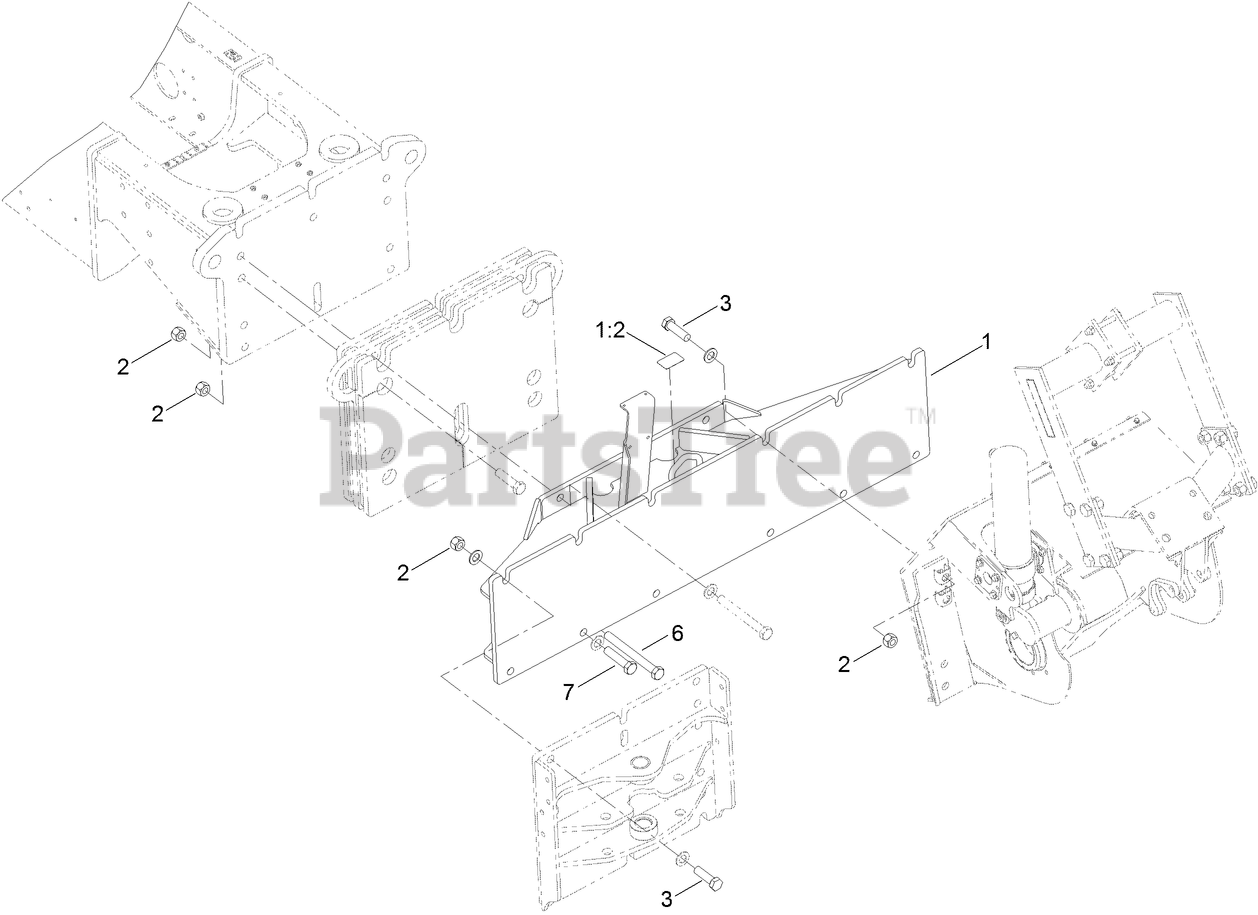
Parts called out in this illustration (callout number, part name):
1	MOUNT-COMBO, RT1200
1:2	DECAL-LIFT/TIE DOWN
3	SCREW-CAP, HH
6	SCREW-HH
